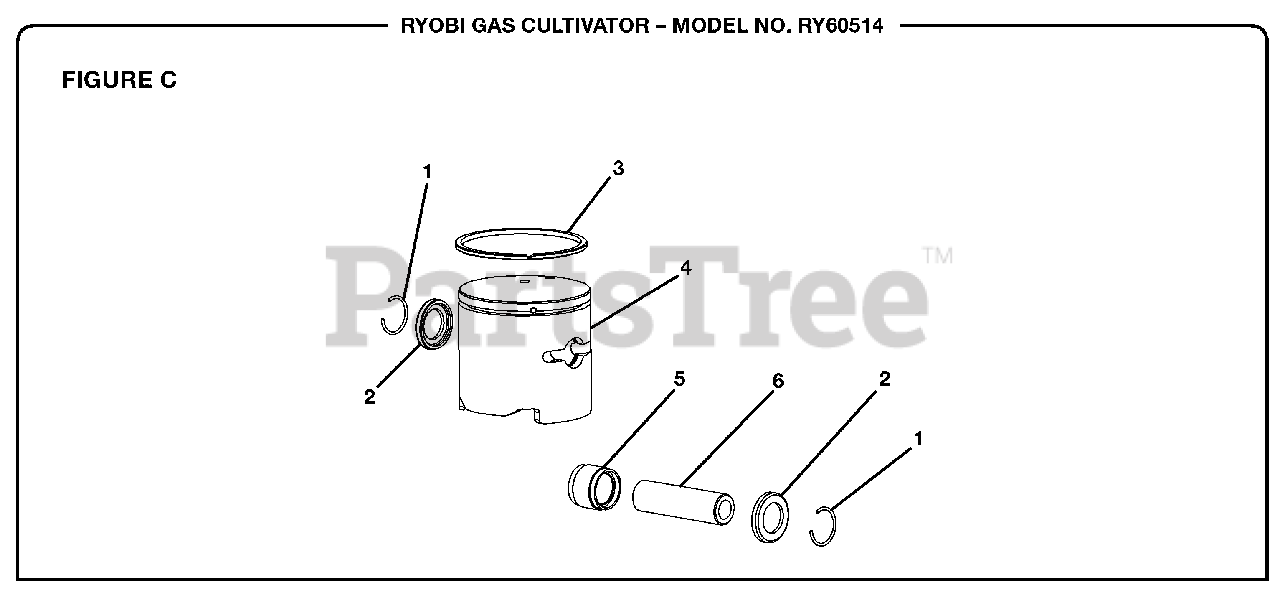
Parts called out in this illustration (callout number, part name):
1	Wrist Pin Clip Ring
2	Washer
3	Piston Ring
5	Needle Bearing (ID 8 x 8.8)
6	Wrist Pin
